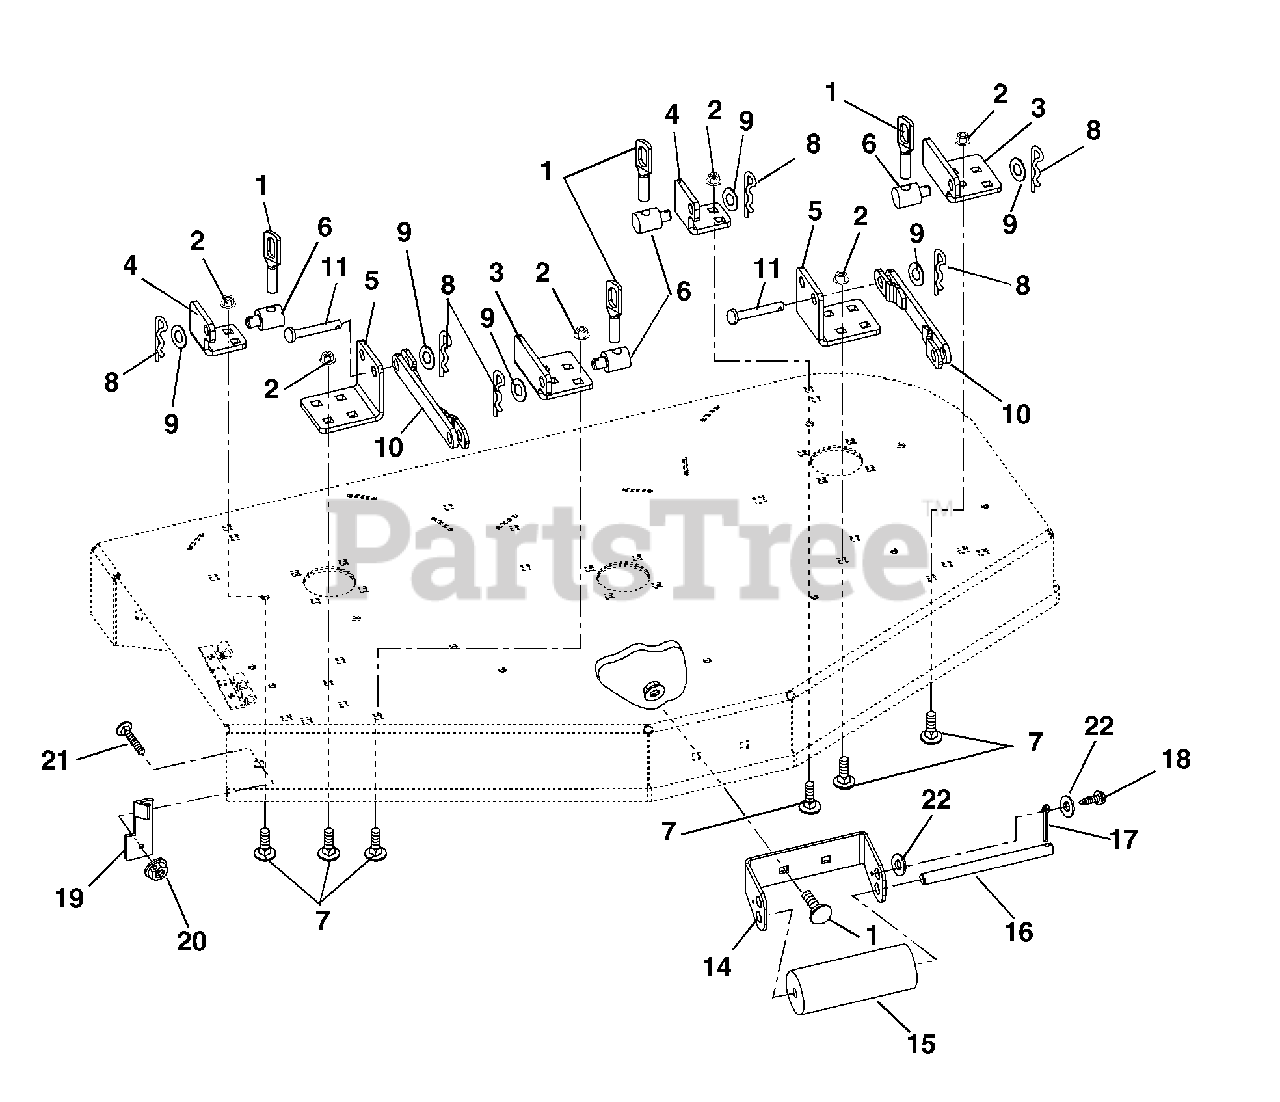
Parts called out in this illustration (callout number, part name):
1	DECK LINK
2	@NUT-LK-NYL-FLG .38-16 YWZC
3	BRACKET, MOUNT,FRONT
4	BRACKET, REAR MOUNT
5	BRACKET, STABILIZER
6	TRUNNION-.50
7	@BLT-RDHDSQNK .38-16X.75 G5YZ
8	PIN, HAIR, EXT - #16 YWZC
9	WSHR-FL-STL.511X1.441X.125 YWZ
10	WMT, STABILIZER ARM
11	PIN-CLEV .494X1.25 YWZC
12	@NUT-LK-NYL-FLG .38-16 YWZC
13	@BLT-RDHDSQNK .38-16X.75 G5YZ
14	BRACKET, ROLLER MOUNT
16	PIN, RETAINER
17	@PIN-CTR .25X1.00 YWZC
18	@SCR-TAP .25-20X.50 HWH TR YWZ
19	BRACKET, CHUTE LOCK
20	@NUT-SPNLK-FLG .375-16 YWZC
21	@BLT-RDHDSQNK .38-16X1.25 G5YZ
22	@WSHR-FL-STL.344X.688X.065YWZC
